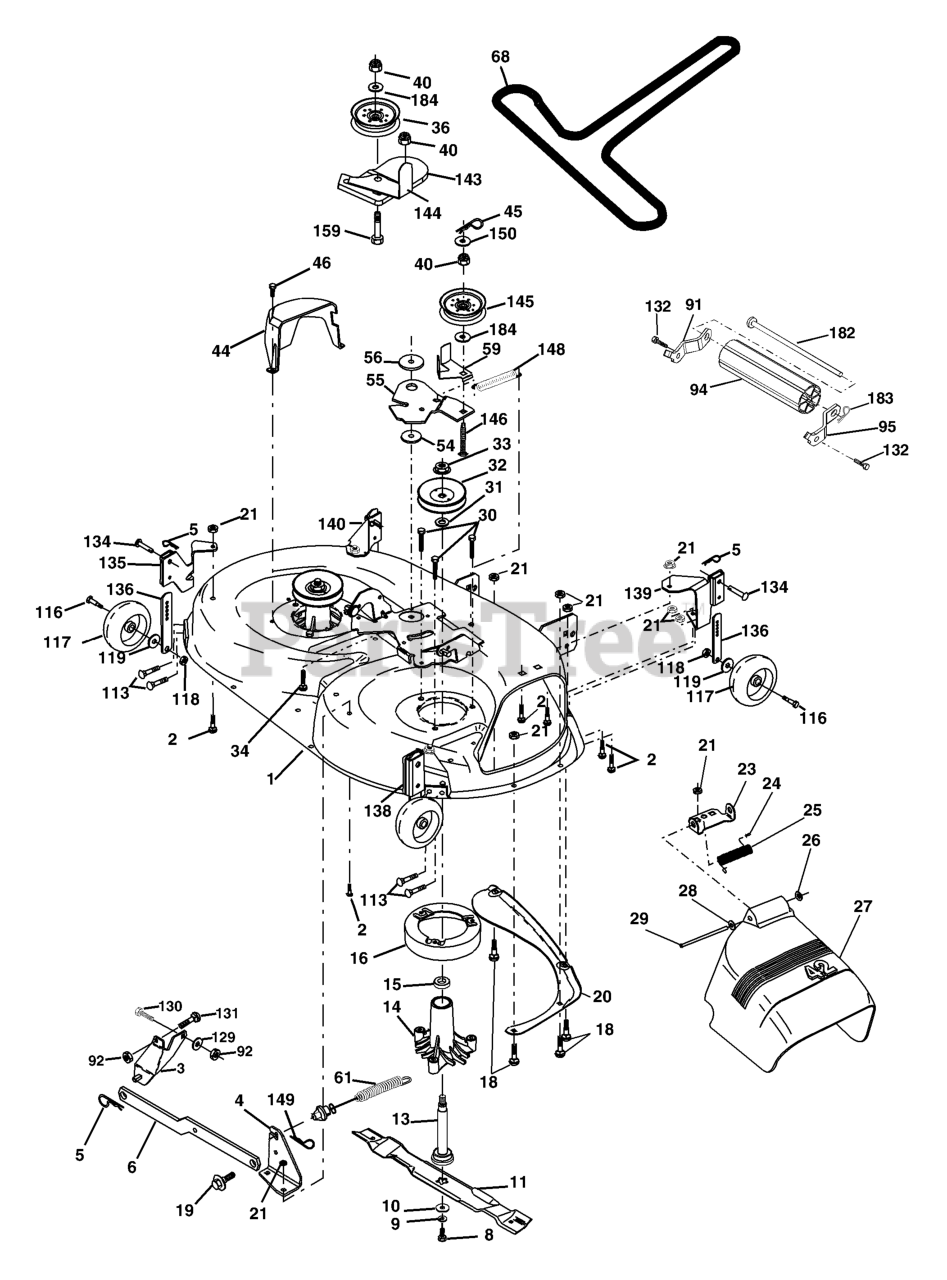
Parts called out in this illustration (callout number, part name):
1	MOWER DECK SHELL 42"
2	RP BOLT 5/16-18 X3/4 ZN/YEL GR
3	BRKT ASM SWAY BAR
4	BRACKET SWAY BAR 42" DECK
5	RETAINER-SPRNG RB
6	BAR SWAY DECK
8	BLADE BOLT
9	LOCKWASHER
10	WASHER.BLADE
11	42" HI-LIFT BLADE
13	SHAFT ASM VENT
14	HOUSING.MANDREL.VENTED (MACHD)
16	STRIPPER.MANDREL.ROUND.BLACK
18	BOLT
19	BOLT SHD 5/16-18
20	BAFFLE.VORTEX
21	LOCKNUT
23	BRKT, DEFL. MOWER
24	CAP-SLEEVE LT
25	SPRING TORSION
26	NUT PUSH M
27	SHIELD DEFLECTOR
28	Washer 11/32 x 5/8 x 16 Ga.
29	ROD.HINGE
30	SCREW, WASHER HEAD
31	WASHER.SPACER.MANDREL
32	PULLEY MANDREL
33	NUT, FLG TOPLOCK 9/16"
34	BOLT.3/8-16X1.50
36	PULLEY.IDLER.FLAT
40	NUT LOCK FLG 3/8-16 UNC
44	GUARD MANDREL LH BLACK
45	RETAINER M
46	SCREW.1/4-20X5/8
55	ARM IDLER 42" MOWER LT/YT
56	SPACER RETAINER
59	GUARD TUV IDLER
61	SPRING EXT ELEC CLUTCH
68	V-BELT PRIMARY 42"
91	BRACKET ASM NOSEROLLER LH
92	NUT
94	NOSE ROLLER
95	BRACKET ASM NOSEROLLER RH
113	SCREW 5/16"
116	BOLT M
117	WHEEL.GAUGE.STANDARD
118	LOCKNUT
119	WASHER.5/16.FLAT.STE.STD.
129	WASHER
130	BOLT
131	BOLT D
132	SCREW, 3/8-16X3/4
134	RIVET.PIN.HEAD.YELLOW.
135	BRACKET ASM, WHEEL
136	BAR.ADJUST.WHEEL.ANTI.SCALP.BL
138	BRACKET.ASM.WHL.GA.R.RH.42".GR
139	BRACKET ASM, WHEEL
140	BRACKET ASM, WHEEL
143	BRACKET, ARM IDLER
144	KEEPER BELT 42" CLUTCH
145	PULLEY.IDLER.FLAT.PLATED
146	BOLT CARRIAGE IDLER
148	IDLER RETURN SPRING
149	SPRING.RETAINER.YELLOW.ZINC
150	WASHER LT
159	BOLT
182	ROD ROLLER NOSE STANDARD
183	SPRING RETAINER
184	WASHER
